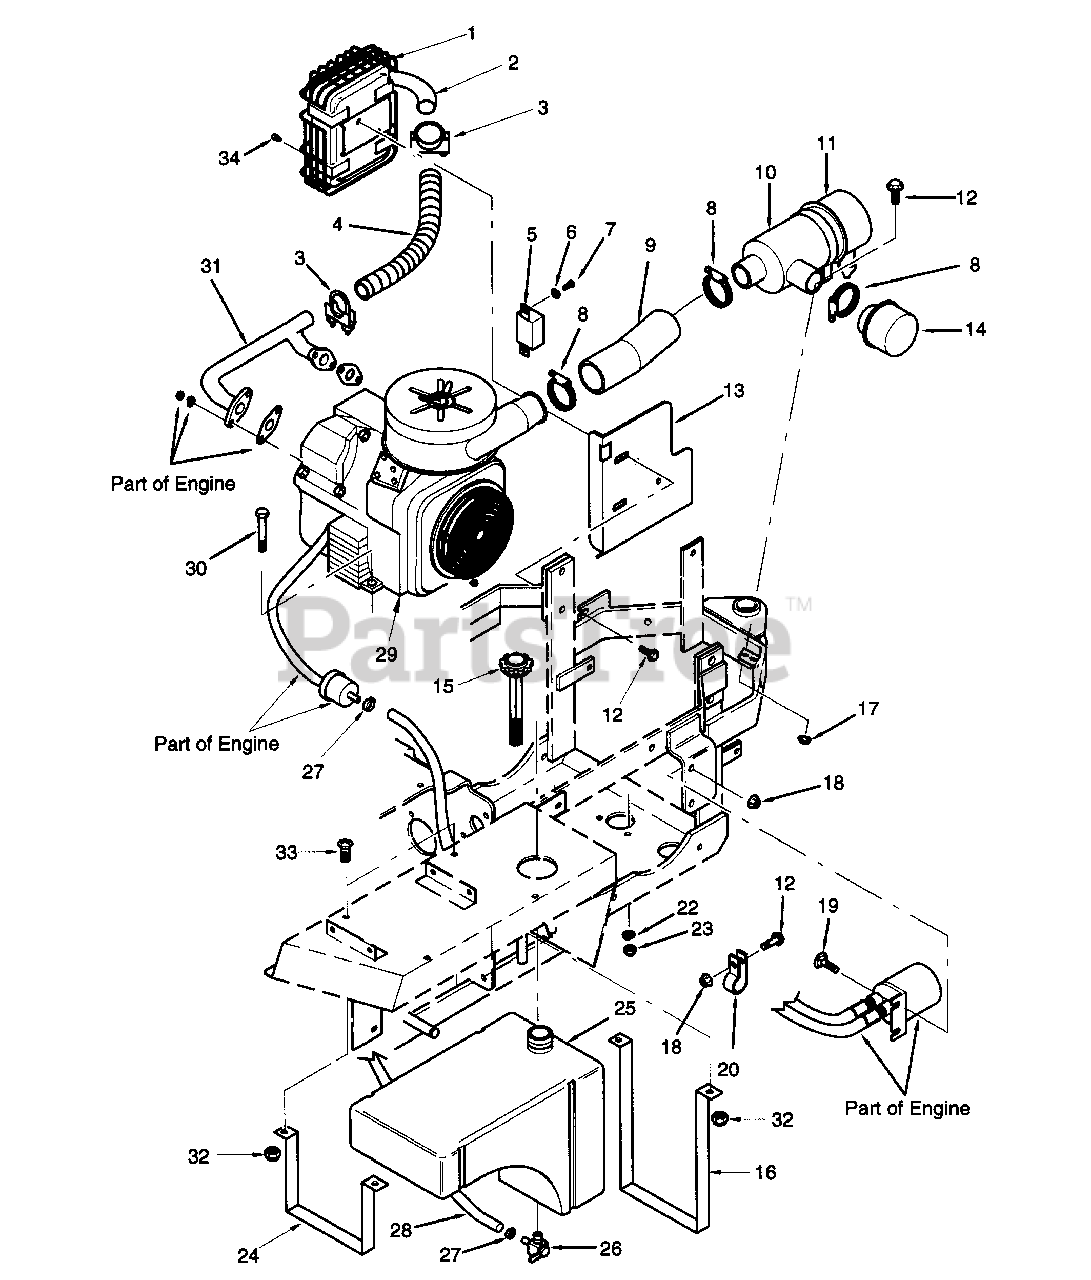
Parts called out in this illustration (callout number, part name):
1	GUARD, MUFFLER
2	MUFFLER
3	CLAMP, MUFFLER
4	EXHAUST PIPE, FLEXIBLE
5	RELAY
6	LOCKWASHER, 1/4
7	MACHINE SCREW, ROUND HEAD, 1/4-20 X 1/2
8	CLAMP, 2.25 DIA
9	HOSE, AIR INTAKE
10	AIR CLEANER ASSEMBLY
11	BAND, AIR CLEANER
12	SERR. FL. HEX HEAD CPSCR, 5/16-18 X 3/4
13	GUARD, MUFFLER
14	PRECLEANER, AIR INTAKE
15	CAP, FUEL TANK, WITH GAUGE
16	STRAP, FUEL TANK - REAR
17	SERR. FL. HEX NUT, 5/16
18	HEX LOCKNUT, ELASTIC STOP, 5/16-18
19	CARRIAGE BOLT, 5/16-18 X 1.00
22	LOCKWASHER, 3/8
23	HEX LOCKNUT, ELASTIC STOP, 3/8-16
24	STRAP, FUEL TANK - FRONT
25	FUEL TANK(INCLUDES 26)
26	VALVE, FUEL SHUT OFF
27	CLAMP, HOSE
28	FUEL HOSE - 20" LONG(ORDER LENGTH)
29	ENGINE, KOHLER - 20 HP(20CH)
29	ENGINE, KOHLER - 22 HP(22CH)
30	BOLT, HEX HEAD, 3/8-16 X 1-3/4
31	MANIFOLD, EXHAUST
33	MACHINE SCREW, ROUND HEAD, 1/4-20 X 2.00
34	CAPSCREW, SOCKET HEAD, #10-32 X 1/2
